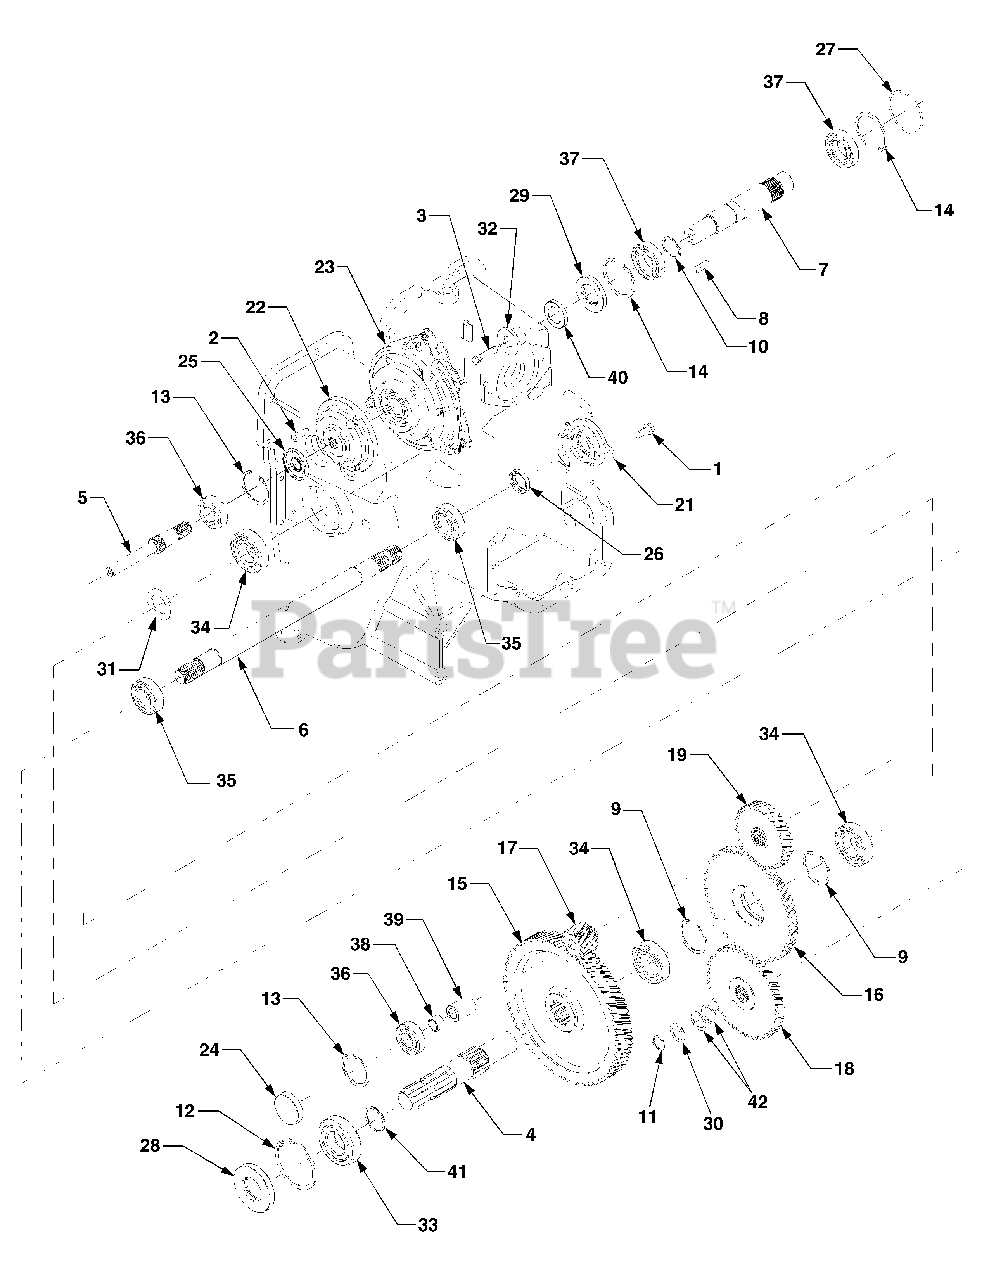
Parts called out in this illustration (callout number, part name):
1	Screw, Hex Wash. Hd. Tapp. 5/16-18 x .875
2	Screw, Socket Hd. 5/16-18 x .75
3	Screw, 12 Pt. Wash. Hd. w/Patch 3/8-16 x 1.25
4	Shaft, 540 PTO
5	Shaft, Clutch Back
6	Shaft, 2000 PTO
7	Shaft, Input PTO
8	Key, Square, 1/4 x 1. 0
9	Ring, Retaining
10	Ring, Retaining
11	Ring, Retaining
12	Ring, Retaining
13	Ring, Retaining
14	Ring, Retaining
15	Gear, 540 PTO, 81T
16	Gear, 2000 PTO , 61T
17	Gear, Pinion, 540 PTO:14T
18	Gear, Pinion, 2000 PTO:54T
19	Gear, Pinion, 2000 PTO:34T
21	Cover, 2000 PTO
22	Adapter, PTO Output
23	Clutch Assy. PTO
24	Plug, Oil, 1.875 x .375
26	Seal, Oil
27	O-Ring, 2.425 ID x .103
28	Seal, Oil
29	Seal, Oil
30	Washer, Flat, .865 x 1.145 x .030 ..
31	Washer, Thrust
32	Spacer, Shoulder
33	Bearing, Ball
34	Bearing, Ball
35	Bearing, Ball
36	Bearing, Ball
37	Bearing, Ball
38	Spacer, 15mm x 20mm x 14mm
39	Spacer, .6 x 1.0 x 1.345
40	Spacer, 1.004 x 1.375 x .25
41	Ring, Retaining
42	Washer, Flat, .915 x 1.37 x .010
